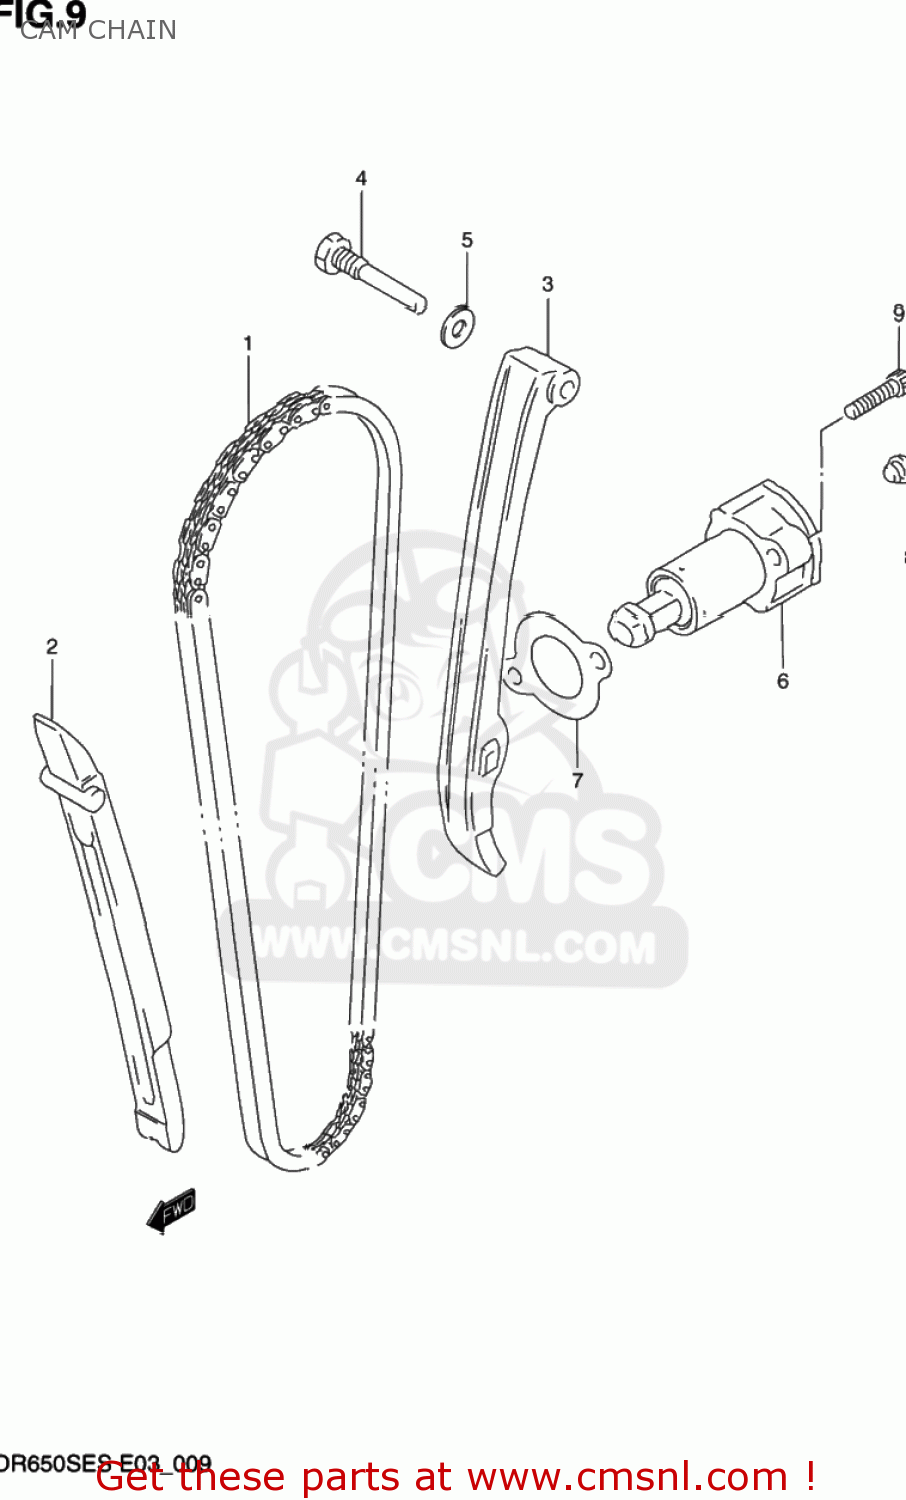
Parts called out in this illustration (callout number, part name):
1	CHAIN,CAMSHAFT DRIVE
2	GUIDE,CAM CHAIN
3	TENSIONER,CAM CHAIN
4	BOLT,CAM CHAIN TENSIONER
5	GASKET 8.2X14X1 (NAS)
6	ADJUSTER ASSY,TENSIONER
7	GASKET,TENSIONER ADJUSTER (NAS)
8	PLUG,ADJUSTER
9	BOLT
